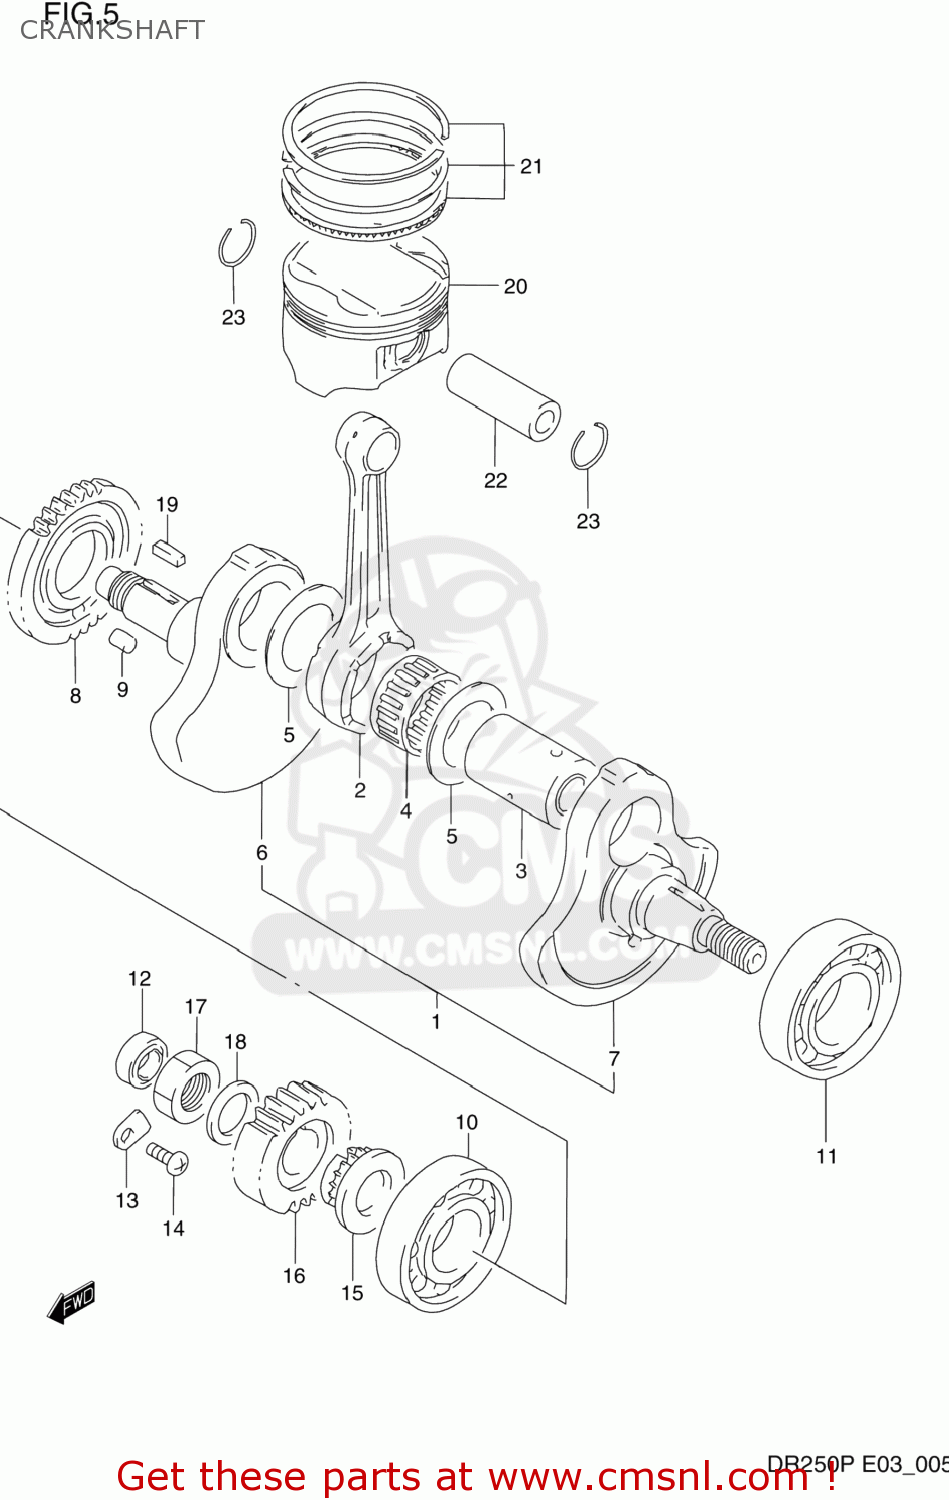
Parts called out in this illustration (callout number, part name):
1	CRANKSHAFT ASSEMBLY
2	CONNECTING ROD
3	PIN COMP,CRANK
4	BEARING(34X43X22)
5	WASHER(34X52X1)
6	CRANKSHAFT,RIGHT
7	CRANKSHAFT,LEFT
8	GEAR,CRANK BAL DRIVE(NT:37)
9	PIN
10	BEARING(30X72X19)
11	BEARING(35X72X17)
12	SEAL,OIL(14X24X6)
13	RETAINER,BEARING
14	SCREW
15	SPROCKET,CAM CHAIN DRIVE
16	GEAR,PRIMARY DRIVE
17	NUT
18	WASHER
19	KEY
20	PISTON
21	RING SET,PISTON
22	PIN,PISTON
23	RING,SNAP
